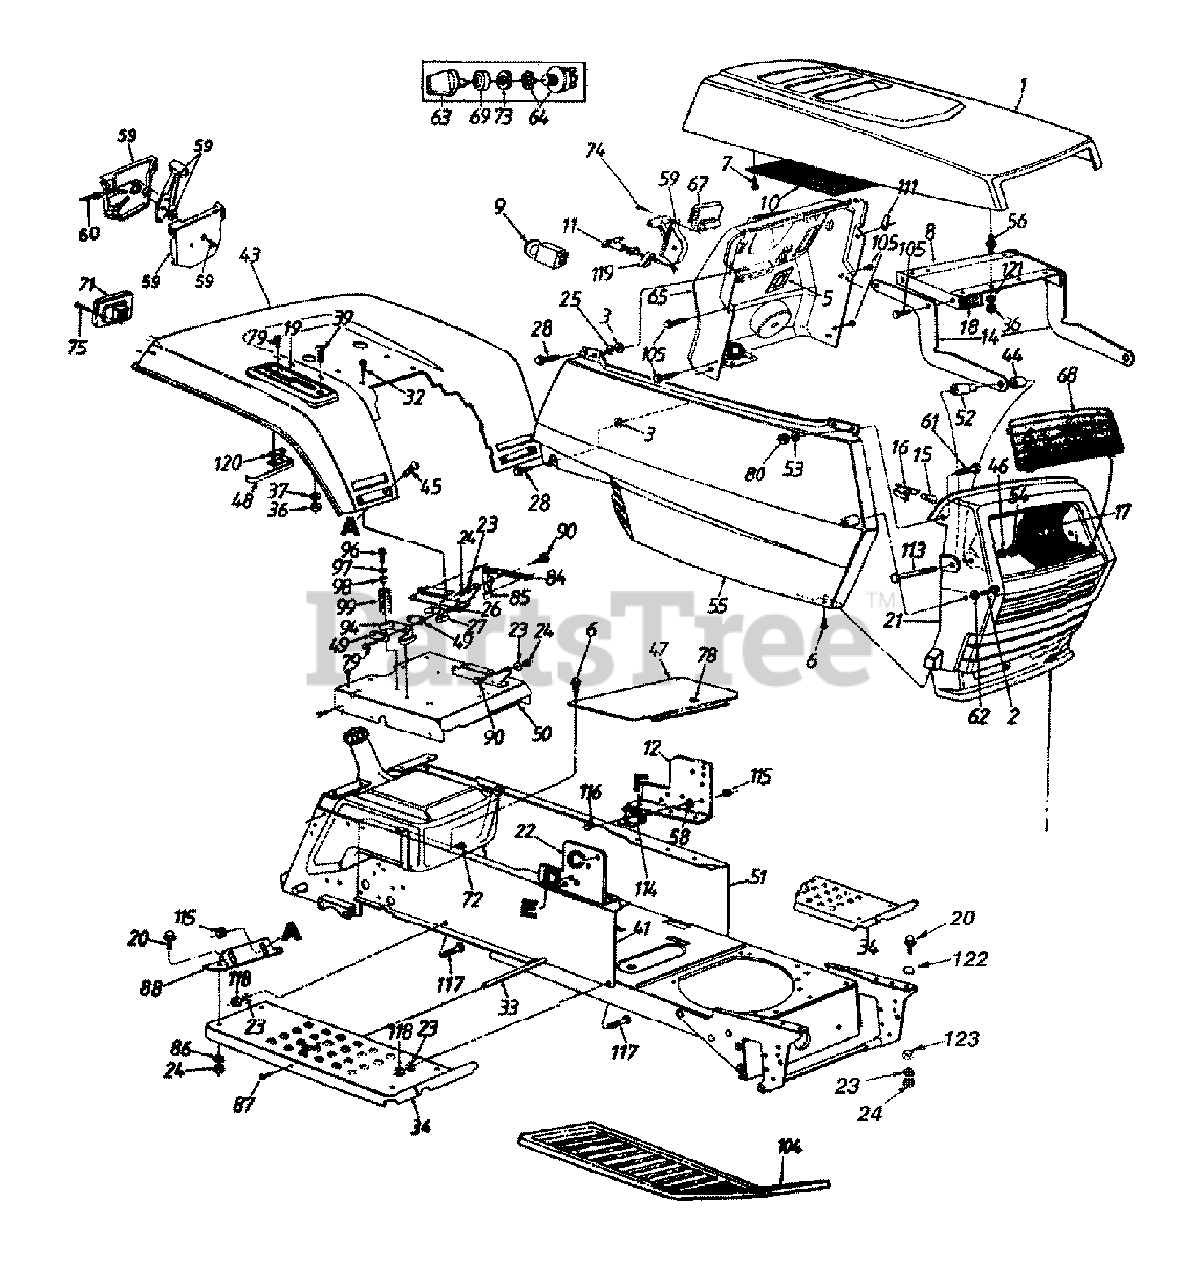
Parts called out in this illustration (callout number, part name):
2	Hex Wash. B-Tap Scr.1/4 x .62" Lg.
3	Bolt Retainer 1/4" I.D.
5	Switch Retainer
6	Truss Mach. B-Tap Scr.#10 x .5" Lg.
7	Hex Wash. Hd. AB-Tap Scr. #8 x .5"
11	Choke Control
16	Twist Lock-Lamp Socket
17	Reflector-Headlight
19	Speed Control Index Brkt.
20	Hex Bolt 5/16-18 x .75" Lg.
21	Grille
24	Hex Sems Nut 5/16-18 Thd.
25	Fl-Wash. 1/4" I.D. x .93" O.D.
26	Insulator Boss Plate
27	Seat Spring Switch
28	Hex Wash. TT-Tap Scr. 1/4-20 x .75"
32	Hex Wash. Hd. AB-Tap Scr.
33	Running Board Rod
37	L-Wash. 1/4" I.D.
39	Truss Mach. Scr. 1/4-20 x 1.0" Lg.
44	Spacer .33" I.D. x .625" O.D.
45	Carriage Bolt 1/4-20 x .50" Lg.
46	Fl-Wash. .328" I.D. x .68" O.D.
49	Insulator Plate
50	Seat Plate
53	Fl-Wash. .281" I.D. x .5" O.D.
54	Hex Cent. L-Nut 5/16-18 Thd.
55	Side Cover Ass'y.-R.H.
56	Double Ended Stud 1/4-20 Thd.
58	Ext. L-Wash. 1/4" I.D.
59	Throttle Control Box Ass'y.
60	Throttle Control Wire 39" Lg.
61	Hex Bolt 1/4-20 x .62" Lg.
62	Fl-Wash. .281" I.D. x .73" O.D.
64	Ignition Switch
67	Ammeter
68	Lens
69	Ignition Switch Cap
71	Taillight Ass'y.
72	Speed Nut #10Z
73	Ignition Switch Nut
74	Truss Mach. AB-Tap Scr.#10 x .5" Lg.
75	Truss Hd. AB-Tap Scr. #6 x .62"
78	Snap Bushing
79	Hex Wash. Hd. AB-Tap Scr. #8 x .50"
80	Hex L-Nut 1/4-20 Thd.
84	Ext. Spring 5.31" Lg.
85	Seat Lift Brkt.
86	Bell-Wash. .345" I.D. x .88" O.D.
87	Truss Machine Scr. 5/16-18 x .75" Lg.
94	Spring Switch
96	Hex Flange TT-Scr. 5/16-18 x .875"
97	Fl-Wash. 5/16" I.D.
99	Compression Spring
105	Hex Tap Scr. 1/4-20 x .5" Lg.
111	Speed Nut 1/4-20 Thd.
113	Hex Bolt 5/16-18 x 2.75"
114	Solenoid
115	Hex Sems Nut 1/4-20 Thd.
116	Hex Bolt 1/4-20 x .5" Lg.
117	Rib Neck Bolt 5/16-24 x .75" Lg.
118	Hex Nut 5/16-24 Thd.
119	Retainer Clip
120	Insulator Nut Plate
121	Bell-Wash. .265" I.D. x .75" O.D.
122	Fl-Wash. .349" I.D. x 1" O.D.
123	Speed Nut .312" I.D.
